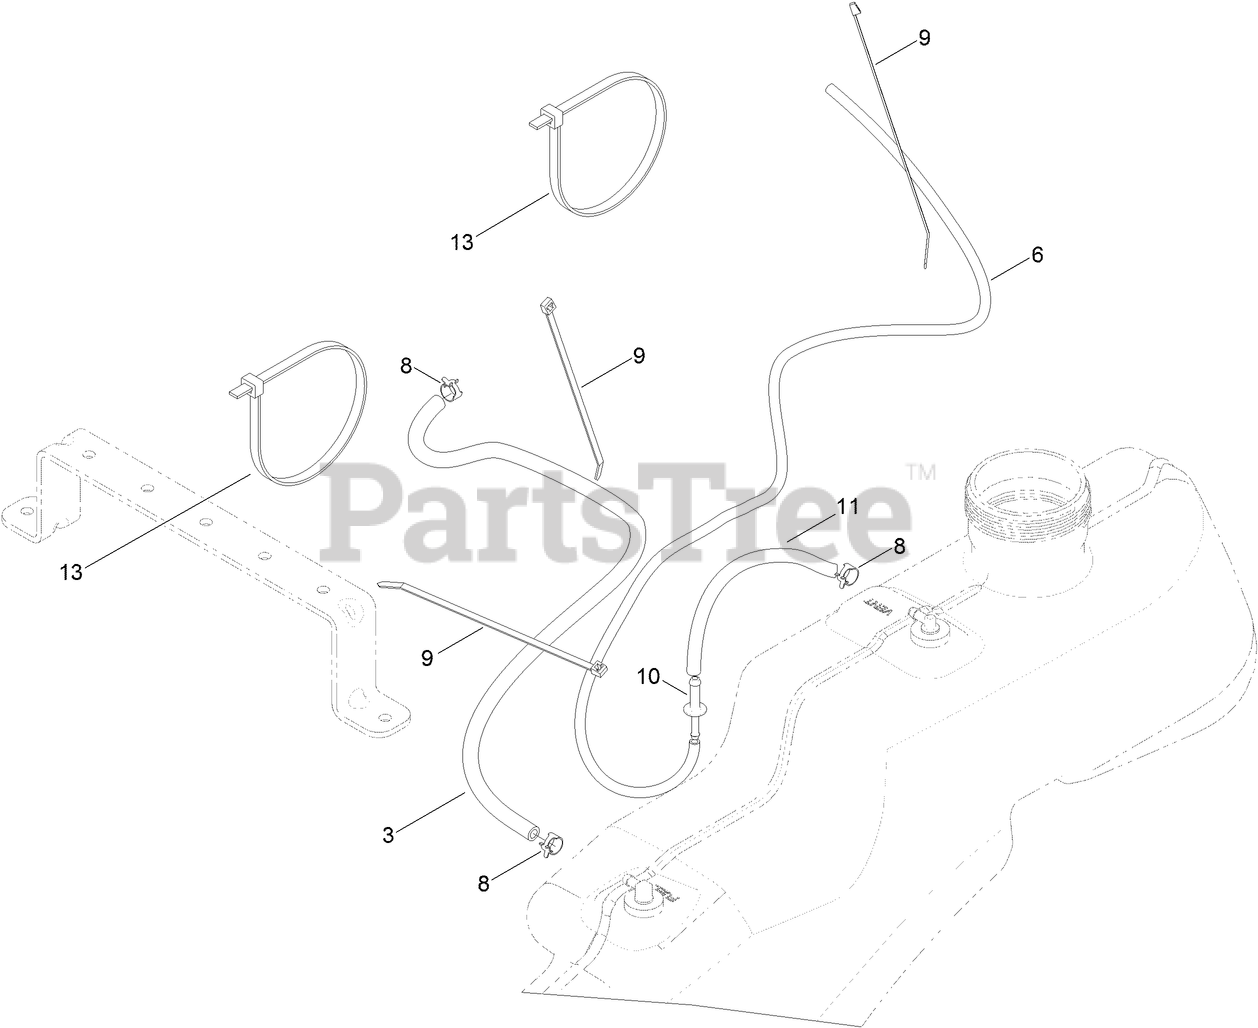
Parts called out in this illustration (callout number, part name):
3	HOSE-FUEL
6	HOSE-FUEL
8	CLAMP-HOSE
9	TIE-CABLE
10	ADAPTOR-ORIFICE
11	HOSE-FUEL
13	TIE-CABLE
